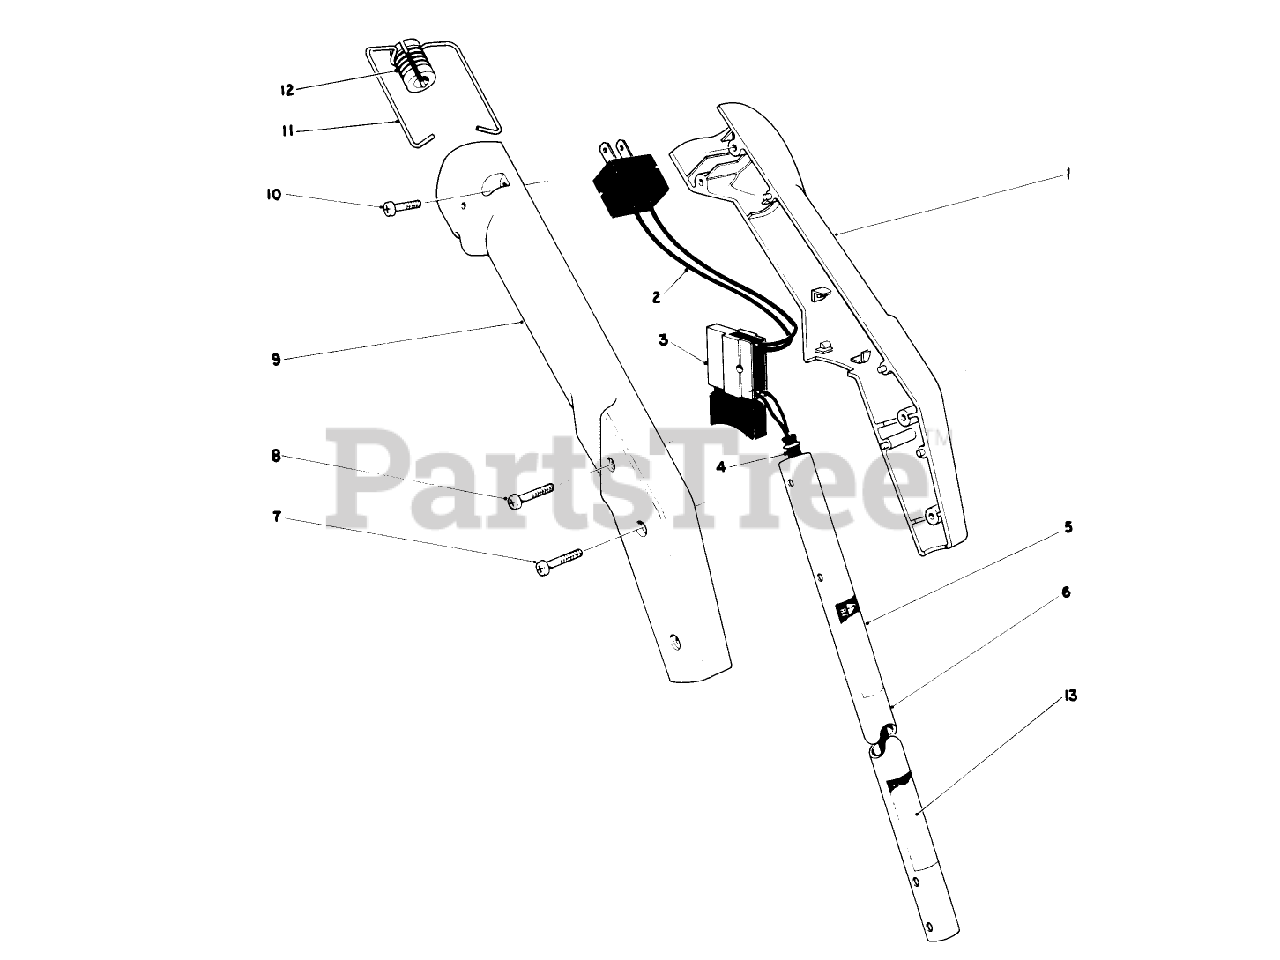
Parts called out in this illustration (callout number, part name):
2	WIRING HARNESS UPPER
3	SWITCH SINGLE SPEED
10	SCREW-PPH
